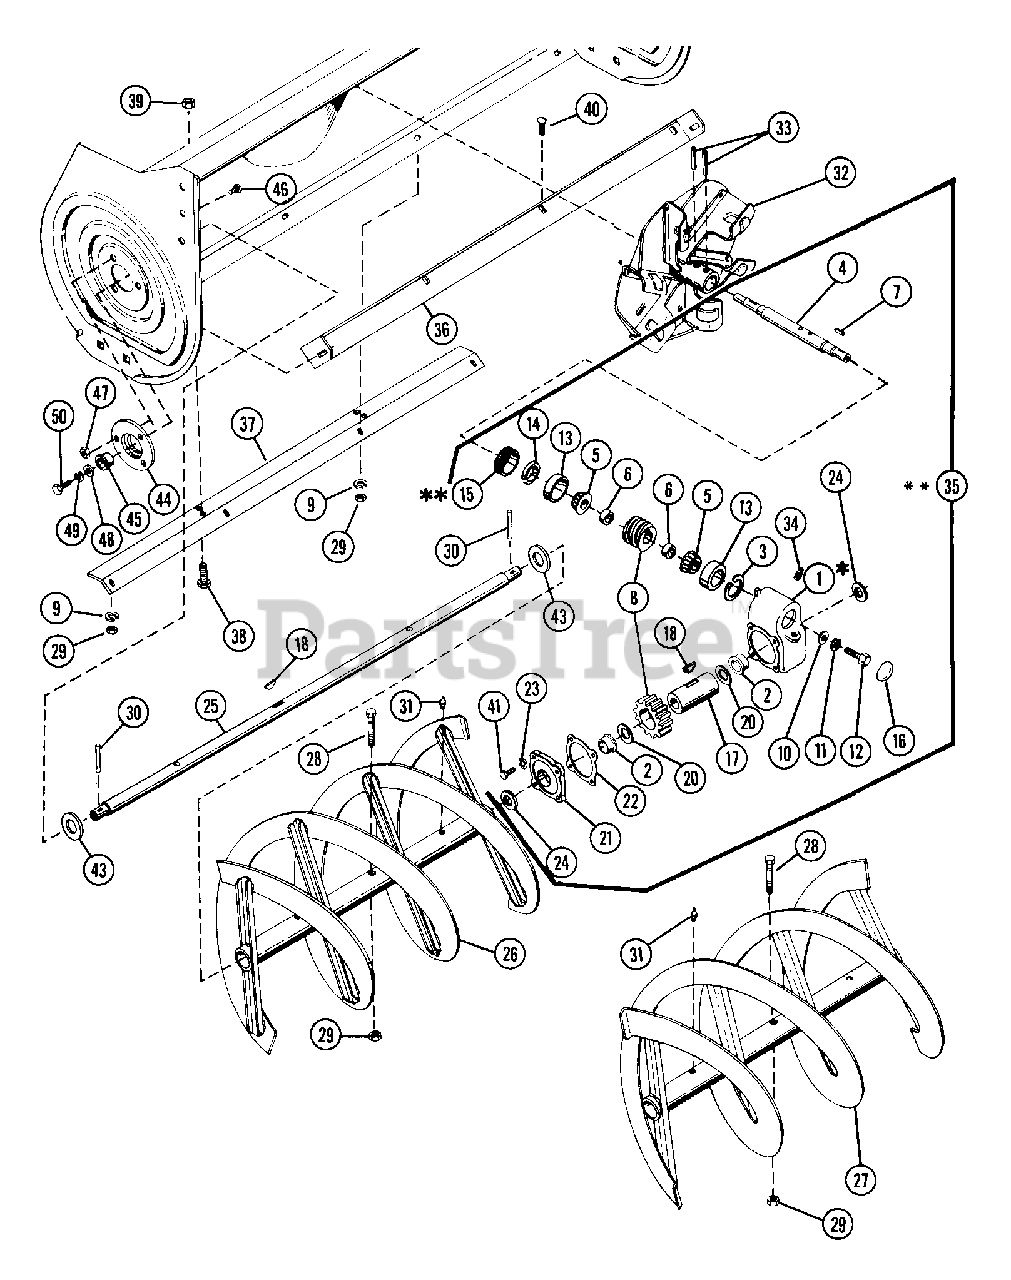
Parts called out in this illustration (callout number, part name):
1	GEAR CASE - CAST IRON
2	BSHG-FLG .683X1.87X1.68X2.250
3	RG-RTNG-INT 1.781X.062
4	WORM SHAFT
5	BRG-CONE .750X.61
6	BSHG, SPCR .755X1.12X.50 PM
7	KEY-SQ .188X1.0X.188 SAE 8630
8	WORM & GEAR SERVICE ASSEMBLY
9	WSHR-FL-STL .38X.875X.083 PL
10	WSHR-FL-STL .328X1.0X.094
11	WSHR-LK .312X.097 PL HVY
12	BLT-HEX .31-18X.75 PL GR2
13	BRG-CUP 1.781X.475
14	SEAL 1.000X1.312X.150
15	ADJUSTMENT PLUG - 1" SHAFT
16	DUST CAP
17	GEAR CASE SHAFT
18	KEY-WDRF .25X.875X.375 SAE A
20	WSHR-FL-STL 1.625X2.500X.012
21	GEAR CASE COVER
23	WSHR-LK-EXT. 250 ID
24	SEAL 1.625X2.125X.250
25	SHAFT, 36" RAKE - 1.00 DIA.
26	RAKE, RIGHT-36"(1ID X 15.75OD)
27	RAKE, LEFT-36"(1"ID X 15.75OD)
28	SHEAR BOLT SERVICE ASSEMBLY
29	NUT-LK .312-18 GR A PL
30	PIN-ROLL .188X1.50
31	SPIN DRIVE ZERK FITTING
32	FAN - 14"
33	PIN-ROLL .313X1.75
34	PIPE PLUG
35	GEAR CASE - 40" - CAST IRON
36	SCRAPER BLADE 36"
37	BLADE BRACE
38	BLT-HEX .38-16X.75 PL GR5
39	NUT-LK TOP .375-16 GR C YWZC
40	BLT-RDHDSQNK .31-18X.75 GR5 PL
41	BLT-HEX .25-20X.75 PL GR2
43	WSHR-FL-STL 1.010X1.505X.062PL
44	BEARING SUPPORT
45	BSHG-FLG 1.000X1.12X.62X1.50BR
46	SCR-SLTR-SERNK .25-20X.62 PL
47	NUT-LK-FLG .250-20 PL
48	WSHR-FL-STL.312X.734X.065PL
49	WSHR-LK .500X.151 HVY PL
50	BLT-HEX .50-13X1.00 PL GR2
